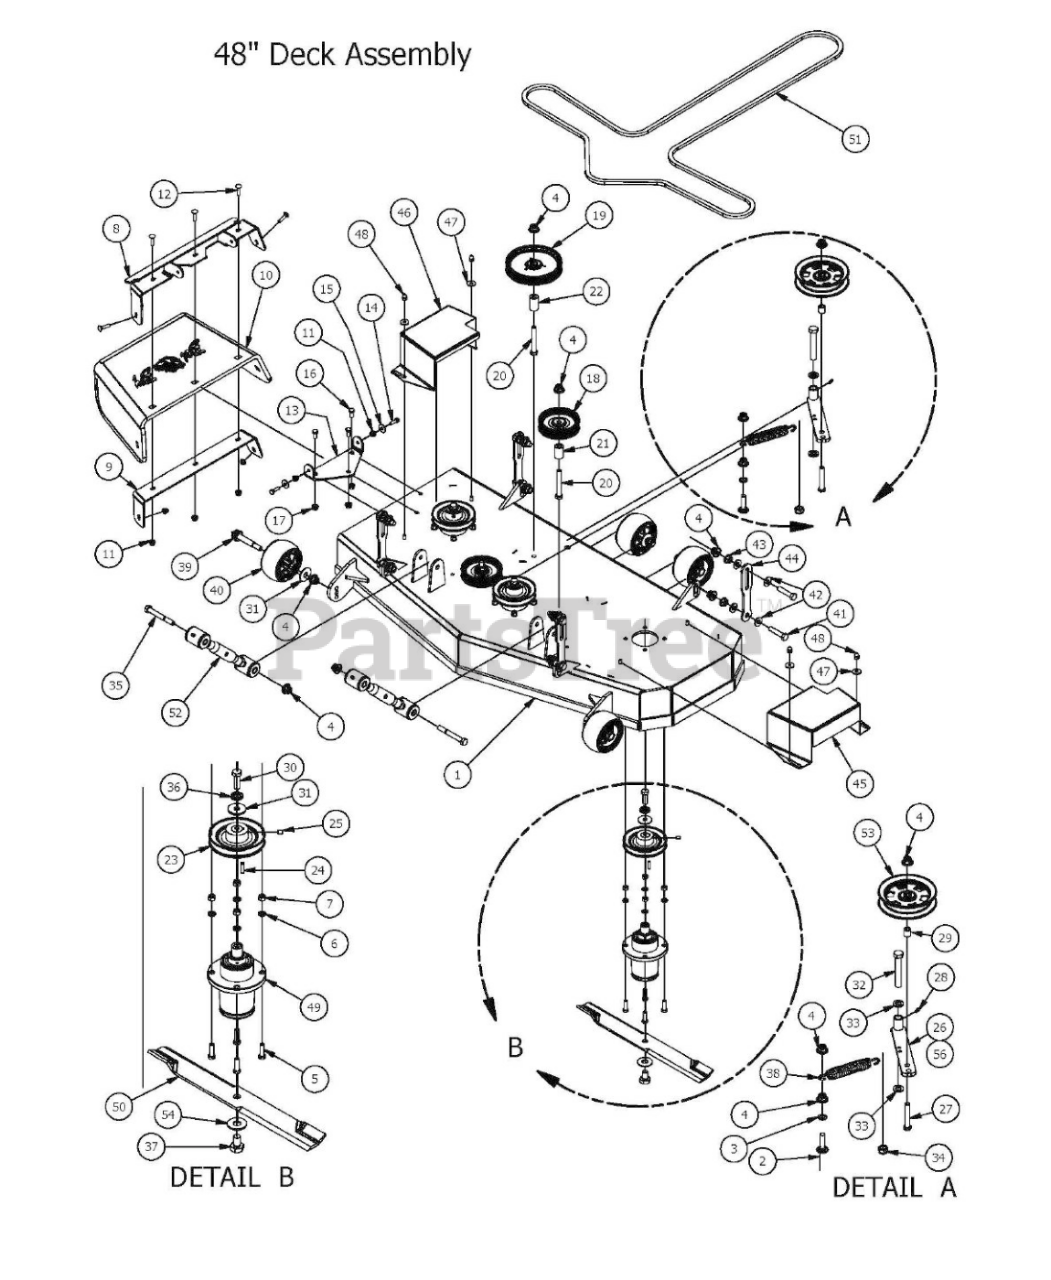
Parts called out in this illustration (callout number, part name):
1	48" Compact Outlaw Deck-Welded Shell
2	1/2 x 2" Carriage Bolt
3	.517 Square Hole Round Washer
4	1/2-13 Nylon Flange Nut
5	3/8" x 1 1/4" Hex Bolt
6	3/8" Lock Washer
7	3/8" Hex Nut
8	Discharge Upper Chute Bracket
9	Discharge Lower Chute Bracket
10	Rubber Discharge Chute
11	5/16" Nylon Flange Nut
12	5/16" x 1 1/4" Carriage Bolt
13	Discharge Chute Hanger (Deck Mounted)
14	5/16" x 1" Bolt
15	.360 ID Plastic Washer
16	3/8" x 3/4" Hex Bolt
17	3/8" Flange Nut
18	4 3/4" Idler Pulley
19	5-3/4 Idler Pulley
20	1/2 x 3 1/2 Flange Bolt Grade 8
21	Idler Pulley Standoff
22	1 3/4" Pulley Spacer
23	5" Spindle Deck Pulley
24	1/4" x 1" Key
25	5/16 Set Screw
26	Deck Idler
27	1/2-13 x GR 5 Hex Bolt Zinc
28	1/4" Press in Grease Fitting
29	Spacer 3/4 OD x 1/2 ID x 314 Length
30	1/2"-20 x 1 1/2 - Grade 5 Fine Thread Bolt
31	1/2" Belleville Washer
32	5/8" x 4" Hex Bolt
33	.630 ID X 1.122 OD X.142 THK Flat Washer Nylon
34	5/8" Nylock (1/2 Jam)
35	1/2" x 4" Bolt (Grade 8)
36	1/2" Lock Washer Zinc
37	5/8" x 1 1/2" Grade 8 Hex Bolt (Fine)
38	2015 Deck Idler Spring
39	Deck Wheel Bolt
40	Anti-Scalp Roller
41	1/2-13X 2-1/4 GR Hex Bolts
42	.505 Nylon Spacer
43	1/2" Flange Nut
44	Deck Hanging Tab longer
45	Pulley Cover Compact Outlaw-Left
46	Pulley Cover Compact Outlaw-Right
47	.360 ID Plastic Washer-Black
48	Acom nut-pulley Cover
49	Spindle Assembly
50	Fusion Blade
51	48 Deck Belt
53	5" Idler Pully
54	5/8" Flat Washer
55	Idler Arm Assembly (Parts 4,26,27,28,29,53)
